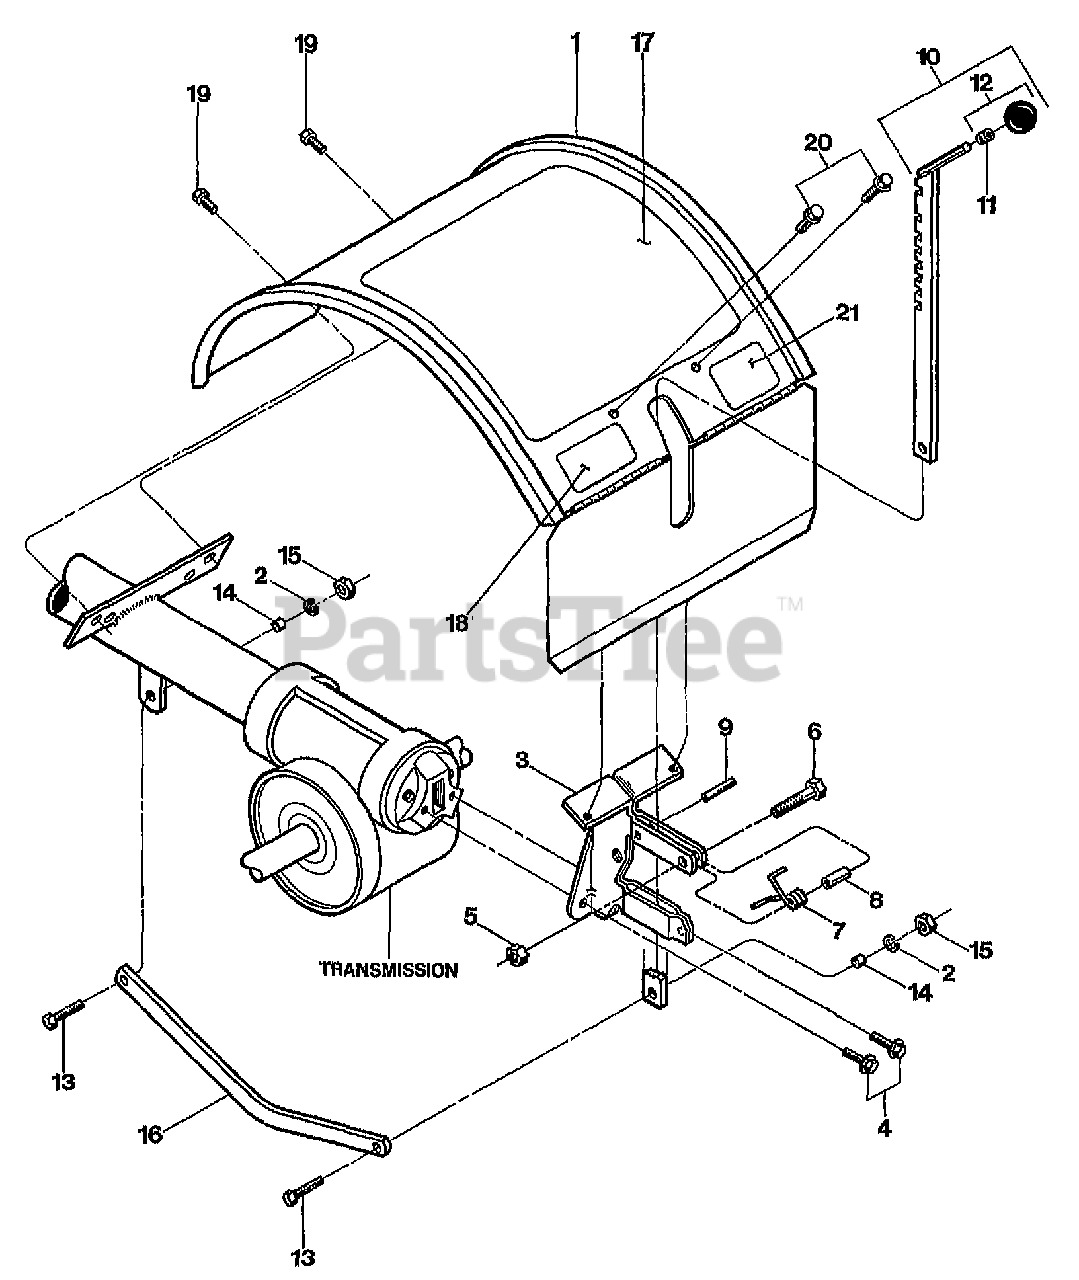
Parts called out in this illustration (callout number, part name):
1	HOOD W/DECALS JR 0PC (INCL. 17,18 & 21
2	WASHER-LK .375 @ DEPL
3	BRKT W/ROLL PIN (9308) (INCL. 9)
4	SCR-HFLK 5/16-18X.75 ZP
5	NUT-LK 1/4-20
6	SCR-HH 1/4-20X1.0
7	SPRING-TORSION
8	SPACER-.250X.343X.375
9	PIN-ROLL .25 X 1 (SPIRAL)
10	DEPTH REGULATOR W/KNOB (INCL. 11 & 12)
11	RING-TOLERANCE .5325 ID
12	KNOB-CONTROL (INCL. 11)
13	SCR-HH 3/8-16X1.25
14	BUSHING-.5X.375X.3
15	NUT-HEX 3/8-16 ZP
16	DRAG BAR-BENT
17	DECAL-HOOD INST JR OPC
18	DECAL-LOGO JUNIOR OPC (MODEL NAME DECAL)
19	SCR-HWH 5/16-18 X .5 STH
20	SCR-HWH 1/4-20 X .5 STH
21	DECAL-TINE WARN SM FRAME
